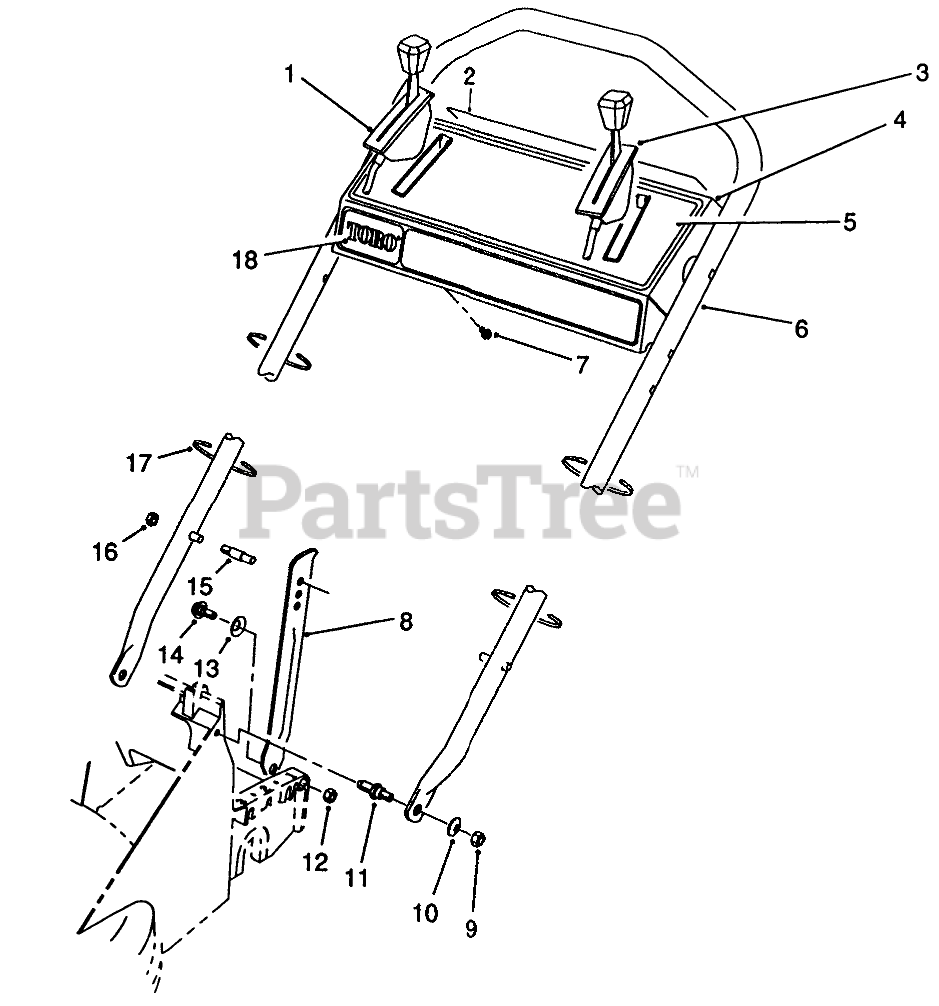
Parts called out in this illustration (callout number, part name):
1	Control-Ground Speed Bend Type #3 Sheath Lg. 51-1/4" Wire Lg. 2-1/8"
2	DECAL - PANEL, REAR
3	ControI-Throttle Bend Type #2 Sheath Lg. 44-3/4" Wire Lg. 2-1/2"
4	Panel-Control
5	DECAL - INSTRUCTION
6	HANDLE
7	SCREW-HWHTF
8	HANDLE LATCH
9	NUT-LOCK
10	WASHER-PLAIN
11	SHOULDER SCREW STUD
12	NUT-LOCK, NI
13	WASHER-BELLEVILLE
14	SHOULDER SCREW LATCH
15	HANDLE PIN
16	NUT-LOCK, NI
17	TIE-CABLE
18	DECAL - TORO PANEL
